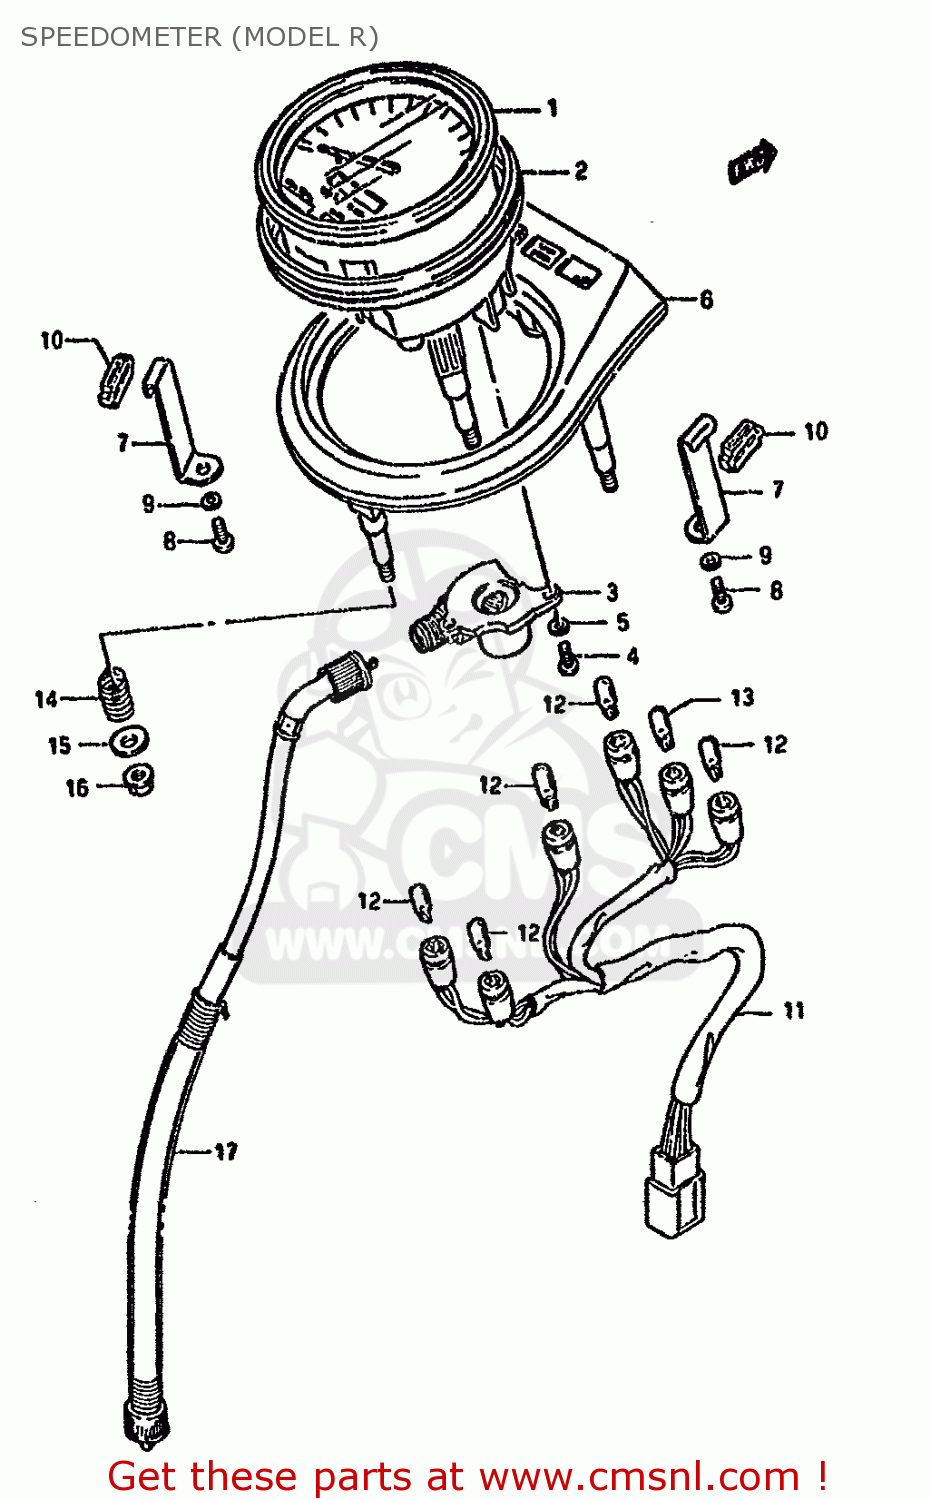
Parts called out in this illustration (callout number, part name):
1	SPEEDOMETER(KILO)
2	CUSHION,METER
3	GEAR BOX,SPEEDOMETER
4	SCREW
5	WASHER,LOCK 4M
6	HOOD,METER
7	BRACKET,METER
8	SCREW
9	WASHER,LOCK 4M
10	CUSHION
11	SOCKET,METER
12	BULB(12V3W,T6.5)
13	BULB(12V1.7W,T6.5)
14	SPRING
15	WASHER (5.5X14X1.2)
16	NUT
17	WASHER,LOCK
18	CABLE ASSY,SPEEDOMETER
